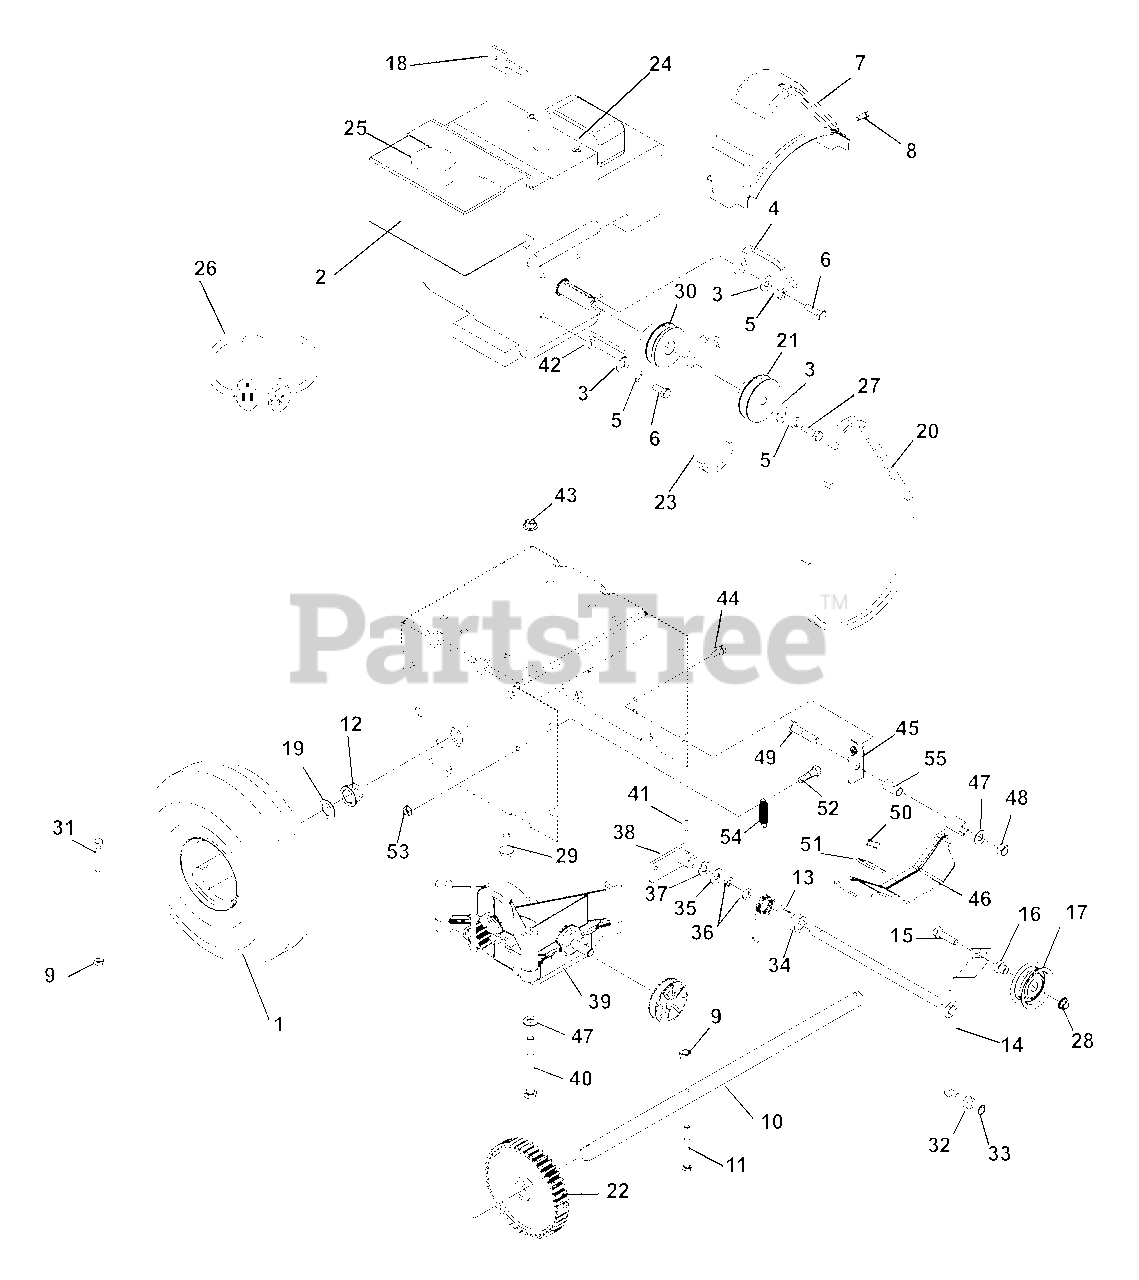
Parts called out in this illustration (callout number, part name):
1	TIRE/WHEEL, 4.10-4
2	ENGINE, 5HP TEC LH195SA 120V
3	@WSHR-FL-STL.38X.875X.083 YWZC
4	FINGER, BELT
5	WSHR-LK .312X.097 HVY YWZC
6	BLT-HEX .31-24X.75 YWZC GR5
7	COVER, BELT
8	@SCR-TAP .25-20X.50 HWH TR YWZ
9	@NUT-LK-CTR .25-20 YWZC
11	BLT-HEX .25-20X2.25 GR8 YWZC
12	BSHG-FLG .750X.873HEXX.53X1.18
13	SG-TORS .067X.88
14	WELDMENT, ATTACHMENT IDLER ARM
15	@BLT-HEX .31-18X1.25 GR5 YWZC
16	SPCR, BRG .315X.50X.688X.281
17	IDLER
18	KEY, PUSH/PULL - TECUMSEH
19	WSHR-FL-STL.754X1.125X.062YWZC
20	V-BELT, 4L-RAW EDGE
21	SHEAVE, ENGINE
22	GEAR, 45T POLYMER
23	V-BELT, 3L-STRETCH FIT
24	PLUG, SPARK
25	CAP, FUEL - TECUMSEH
26	CORD, ELECTRIC START CORD 120V
27	BLT-HEX .31-24X1.00 GR5 YWZC
28	@NUT-LK-TOP-FLG .31-18 YWZC
29	SCR-TAP .38-16X1.0 HWH YZ W/VT
30	SHEAVE, DRIVE
31	BLT-HEX .25-20X1.75 GR8 YWZC
32	BSHG,SLV .265 X .625 X .375
33	RG-RTNG-EXT .250X.010
34	BSHG-SLV .510X.751X.475
35	WSHR-FL-STL .52X.827X.062 YWZC
36	BUSHING, POLYLINER-.50 SNAPIN
37	WSHR-WAVE .50X.75X.015 .13FRHT
38	LEVER, ATTACHMENT CLUTCH
39	TRANSMISSION, FR SS
40	@BLT-HEX .38-16X3.50 GR5 YWZC
41	PIN-GRV .156X.875 TYPE H LC
42	BELT FINGER
43	NUT-LK-CTR-FLG .38-16 YWZC
44	@SCR-TAP .25-20X.50 HWH TR YWZ
45	BRACKET, MOUNT - BRAKE
46	ARM, BRAKE
47	@WSHR-FL-STL.406X.812X.065 YWZ
48	@NUT-LK-CTR .38-16 YWZC
49	@BLT-HEX .38-16X1.75 GR5 YWZC
50	RVT-POP .187X.45 DOME ALUM
51	PAD, BRAKE
52	BLT-SHLDR .31X.50 .25-20X.438
53	@NUT-SPNLK-FLG .25-20 YWZC
54	SG-TENS .06X.46X2.00
55	BSHG-SLV .385X.500X1.045
